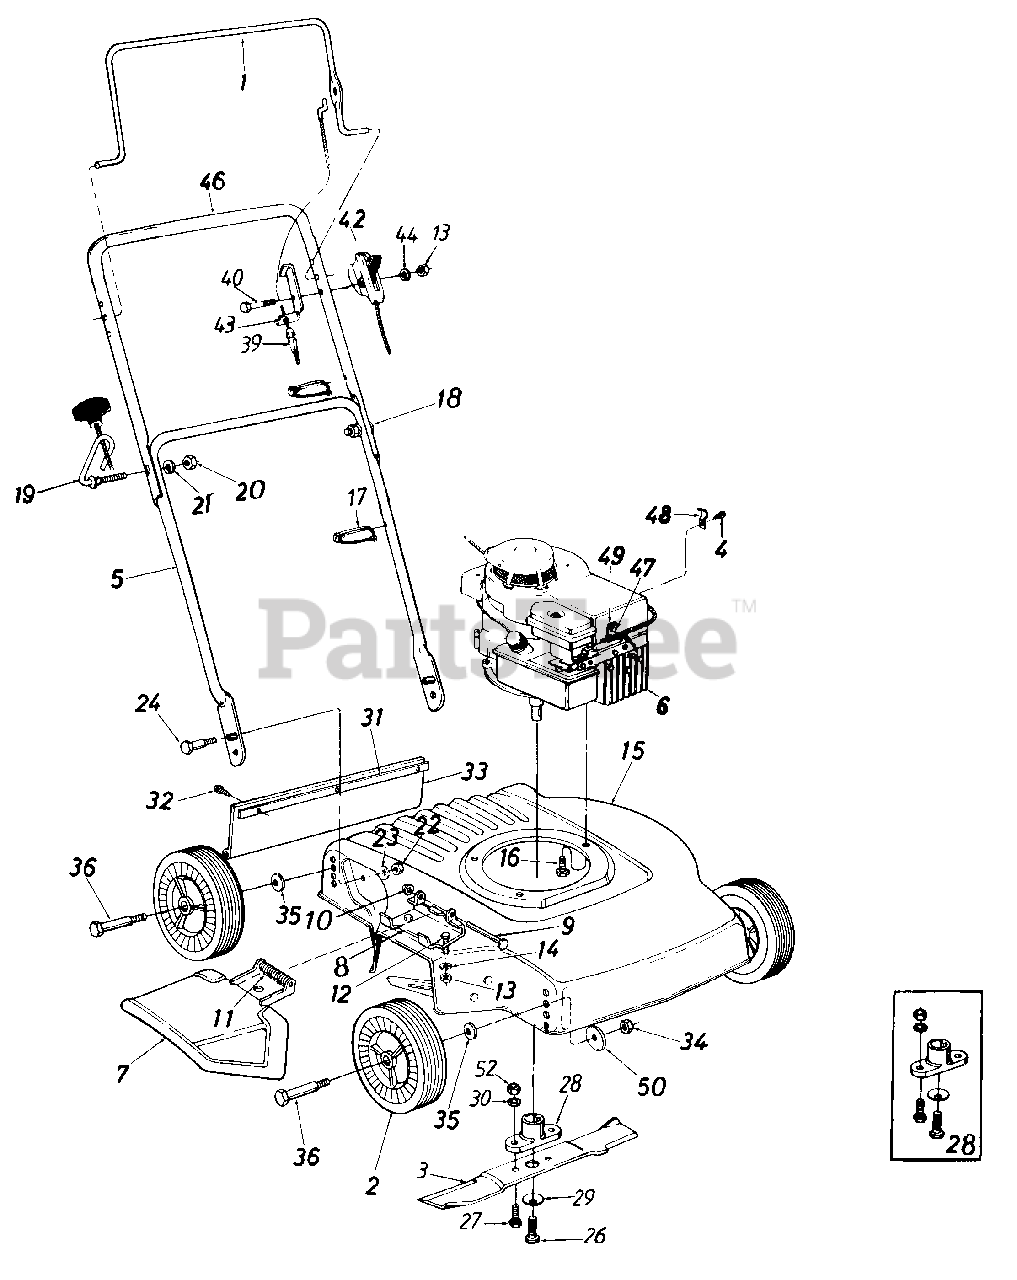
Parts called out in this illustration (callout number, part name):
1	Control Handle-L.H.
3	18" Blade
4	Hex Wash. Hd. AB-Tap Scr. #8 x .50" Lg.
5	Lower Handle
6	Engine
7	Chute Deflector Ass'y. Comp.
8	Adapter Plate
9	Pivot Pin
10	Push Nut 1/4" Rod
11	Torsion Spring
12	Hex Bolt 1/4-20 x .50" Lg.*
13	Hex Nut 1/4-20 Thd.*
14	L-Wash. 1/4" I.D.*
15	18" Deck Ass'y.
16	Hex Wash. Hd. TT-Tap Scr. 3/8-16 x 1.00" Lg.
17	Cable Tie
18	Curved Carriage Bolt 5/16-18 x 1.38" Lg.
19	Rope Guide Bolt
20	Hex Nut 5/16-18 Thd.*
21	L-Wash. 5/16" I.D.*
22	Hex Ins. L-Nut 5/16-18 Thd.
23	Bell-Wash. .345" I.D. x .88"
24	Shoulder Bolt .437" Dia. x .180
26	Hex Bolt 3/8-24 x 1.5" Lg. (Grade 5)
27	Hex Bolt 3/8-24 x 1" Lg.
28	Blade Adapter Kit
29	Bell-Washer 3/8" I.D.
30	L-Wash. 3/8" I.D.
31	Retaining Strip
32	Hex Wash. Hd. AB-Tap Scr. 1/4" x .62" Lg.
33	Rear Flap Ass'y.
34	Hex Nut 3/8-16 Thd.
35	Bell-Wash. .400" I.D. x .88" O.D.
36	Shld. Bolt .498" Dia. x 1.450" Lg.
39	Control Cable-36"
40	Hex Bolt 1/4-20 x 1.75" Lg.
42	Throttle Control Ass'y. Comp.
43	Cable Mounting Brkt.
44	Spr. Wash. .27" I.D. x .57" O.D.
46	Upper Handle
47	Hex B-Tap Scr. #10 x .38" Lg.
48	Casing Clamp
49	Casing Clamp
50	Fl-Wash. .398" I.D. x 1.13"
52	Hex Nut 3/8-24 Thd.
